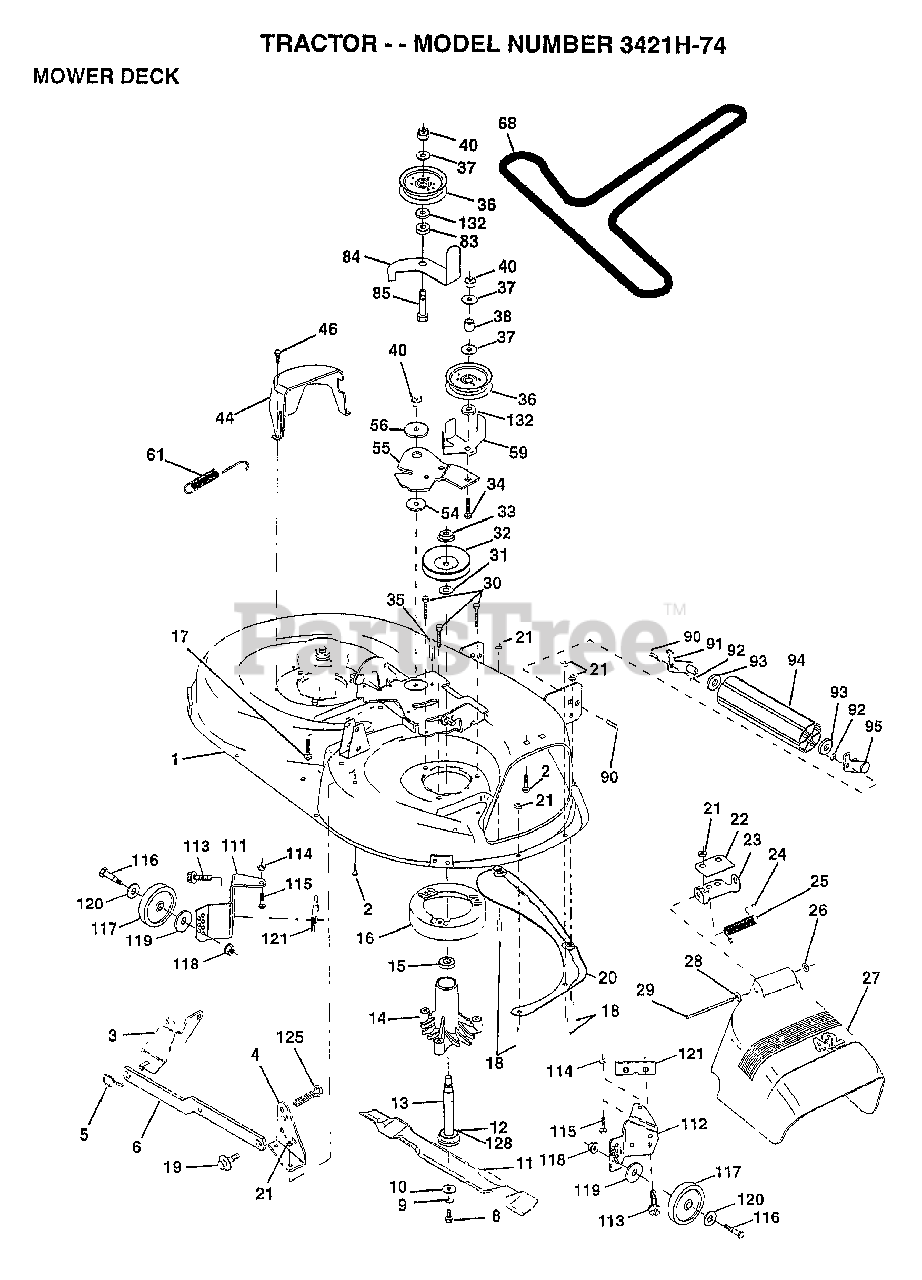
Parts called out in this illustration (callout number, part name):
1	DECK.WELD.42.
2	BOLT
3	BRKT ASM SWAY BAR
4	BRKT DECK SW BAR
8	BLADE BOLT
10	WASHER.HARD.BLADE
11	"BLADE.42"" HIPERF"
12	BEARING.BALL
14	HSG ASM MANDREL
15	BEARING
16	STRIPPER RND MWR
17	BOLT CARRIAGE
18	BOLT
19	BOLT SHD 5/16-18
22	STIFFENER BRKT
23	DEFLECTOR BRKT
24	CAP-SLEEVE LT
25	SPRING TORSION
26	NUT PUSH M
27	DEFLECTOR.SHIELD
28	WASHER
29	HINGE ROD
31	WASHER
32	PULLEY.MANDREL.42
34	BOLT
35	XMAS TREE FASTNER
36	FLAT IDLER PULLEY
37	WASHER
44	GUARD MAND LH BLK
46	SCREW.1/4-20X5/8
54	HARDENED WASHER
56	SPACER RETAINER
59	GUARD IDLER TUV
61	SPRING.EXTENSION
68	BELT.V.T-PATH
83	WASHER
84	"KEEPER-BELT,FIXED"
85	BOLT RDHD 3/8-16
90	BOLT
92	NUT
93	WASHER
111	BRACKET.GWHL.LH.
112	BRACKET.GWHL.RH.
113	SCREW
116	BOLT M
117	WHEEL.GAGE.BLK.PL
118	LOCKNUT
119	WASHER
120	WASHER
121	BRACKET.EXTRD.GWL
128	WASHER.FELT.
132	WASHER GT
